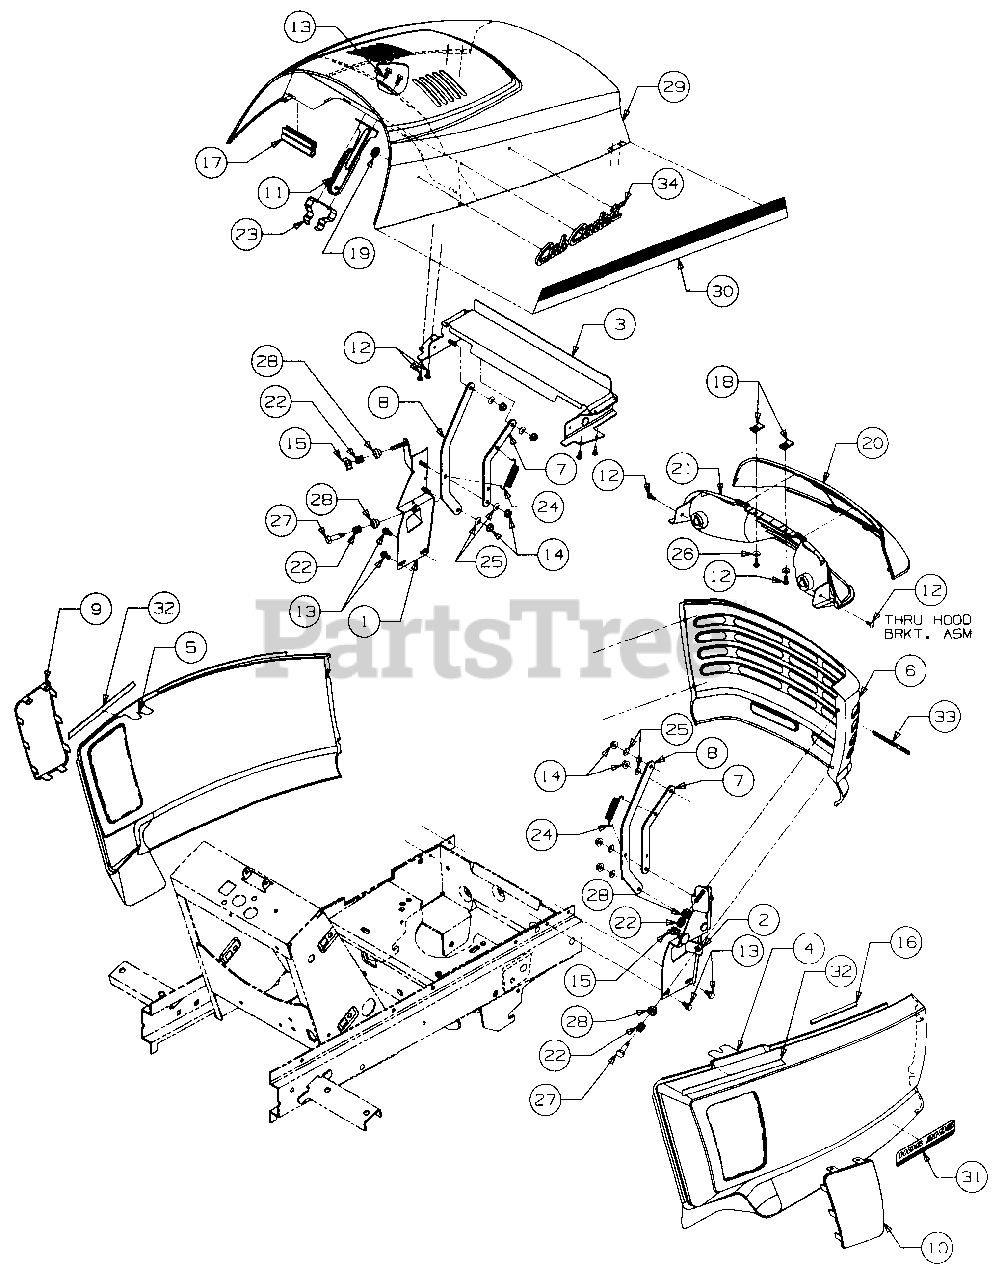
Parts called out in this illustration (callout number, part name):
1	Bracket, Grille LH
2	Bracket, Grille RH
8	Link, Long Hood
12	Screw, Truss Mach Tapp, #10 x .50 Lg
13	Screw, Hex Wash Tapp, 1/4 x .50 Lg
14	Nut, Hex Flange Lock, 1/4-20
15	Nut, Wing, 1/4-20
16	Guard, Trim 4 in. Lg
17	Seal, Heat Baffle
18	Nut, U-Type Speed, #10
19	Retainer, Push Nut
20	Lens, Cub Cadet
21	Reflector, Headlight
22	Spring, Compression, .50 OD x .50 Lg
23	Spring, Hood Latch
24	Spring, Extension, .50 OD x 2.25 Lg
25	Washer, Spring, .265 x .562 x .025 Thk
26	Washer, Flat, .218 x .62 x .063 Thk
27	Bolt, Shoulder, .31 Dia x .75 Lg
28	Bushing, Tapered
31	Graphic, HDS 2185
32	Strip, Protective
33	Graphic, Warning Hot
34	Script w/Studs, Cub Cadet
